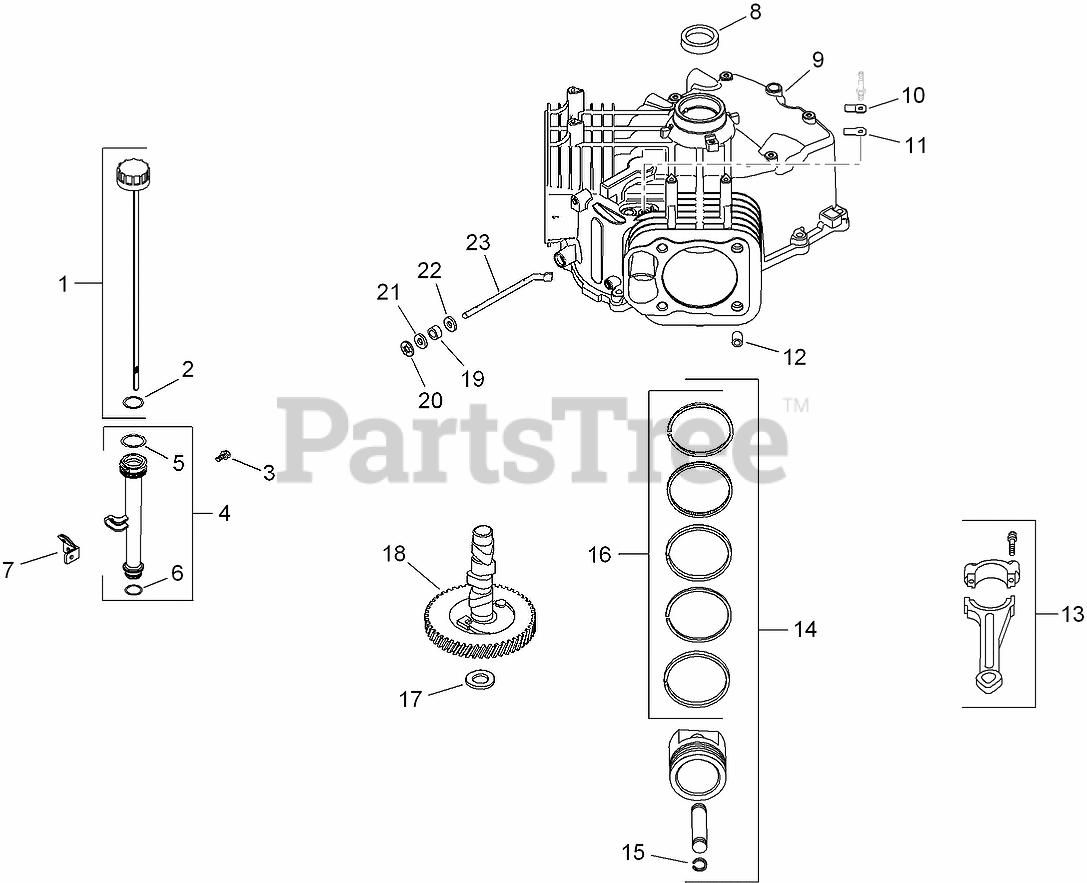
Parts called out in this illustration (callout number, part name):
1	Dipstick ASM (INCLUDES 21, 22)
2	O-RING (DIPSTICK)
3	SCREW-FLG, THD FRM (M5X0.8X13)
4	OIL FILL TUBE ASM
5	O-RING (UPPER OIL FILL TUBE)
6	O-RING (LOWER OIL FILL TUBE)
7	BRACKET-TUBE, OIL FILL
8	SEAL-OIL (HELIX LIP)
9	SHORTBLOCK (SV710-740 REPLACEMENT)
10	RETAINER-REED, BREATHER
11	REED-BREATHER
12	PIN-LOCATING
13	ROD-CONNECTING (STD)
14	PISTON W/RING SET (STD)
14	PISTON W/RING SET (.08)
14	PISTON W/RING SET (.25)
15	RETAINER-PIN, PISTON
16	PISTON RING SET (STD)
16	PISTON RING SET (.25)
17	SHIM-CAMSHAFT (WHITE .028)
17	SHIM-CAMSHAFT (BLUE .03)
17	SHIM-CAMSHAFT (RED .032)
17	SHIM-CAMSHAFT (YELLOW .034)
17	SHIM-CAMSHAFT (GREEN .036)
17	SHIM-CAMSHAFT (GRAY .038)
17	SHIM-CAMSHAFT (BLACK .04)
18	CAMSHAFT KIT
19	SEAL-CROSS SHAFT, GOVERNOR
20	RETAINER-RING
21	WASHER-FLAT (9MM)
22	WASHER-FLAT (11/32)
23	SHAFT-CROSS, GOVERNOR
